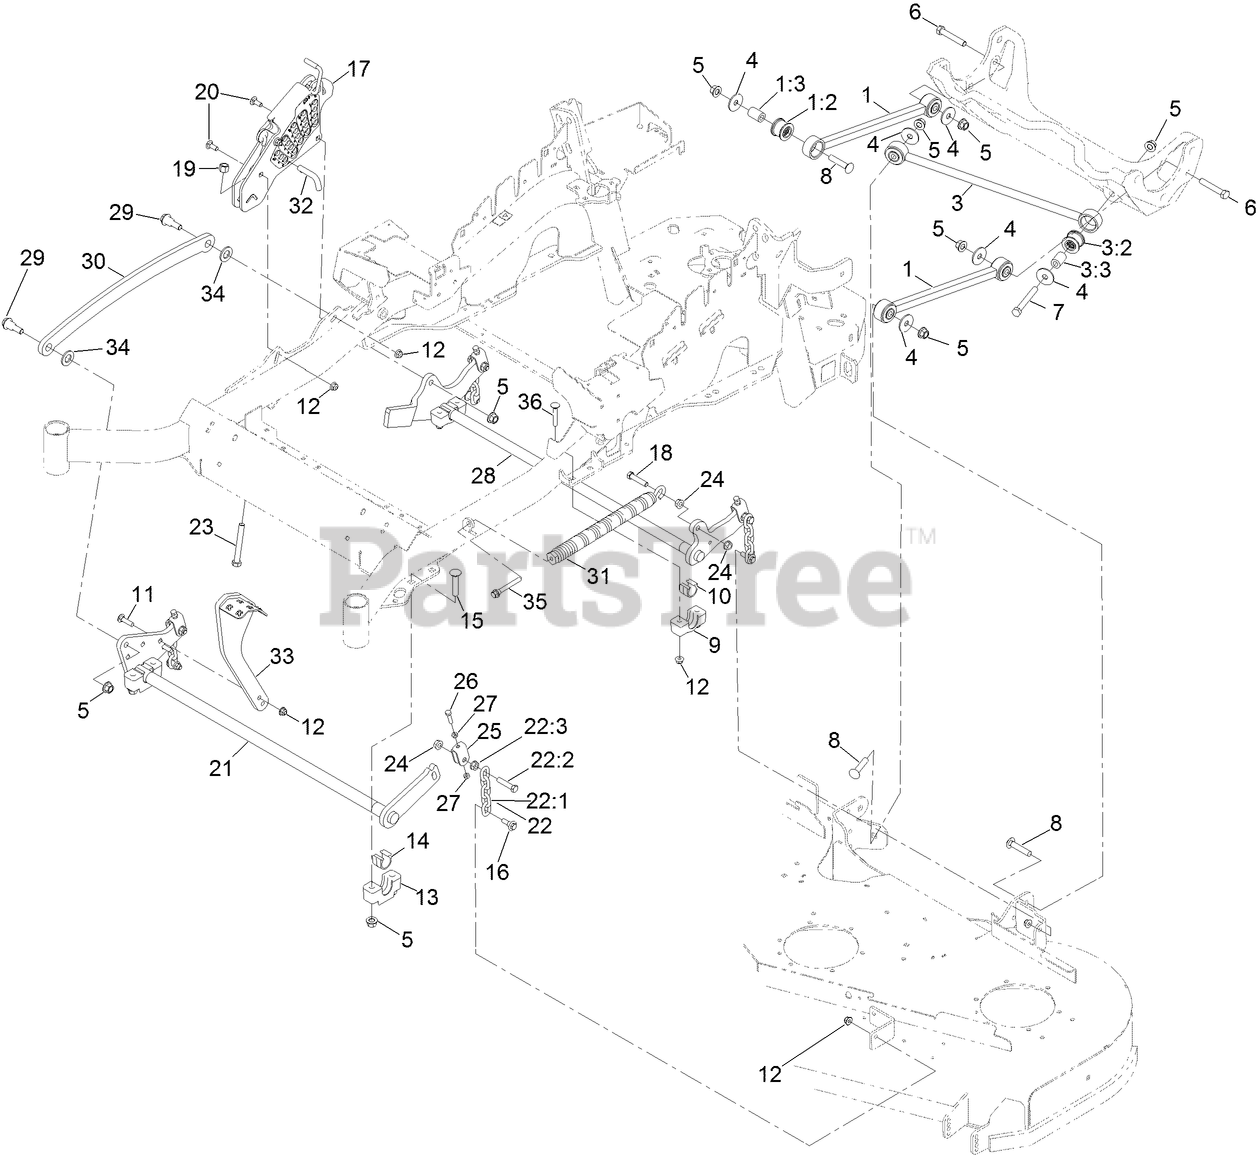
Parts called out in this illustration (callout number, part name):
1	LONG STRUT ASM
1:2	BUSHING-SUSPENSION, RUBBER
1:3	SPACER
3	PANHARD ROD ASM
3:2	BUSHING-SUSPENSION, RUBBER
3:3	SPACER
4	WASHER-THRUST
5	NUT-LOCK
6	SCREW-HH
7	SCREW-HH
8	SCREW-CARR
9	SUPPORT-CROSS SHAFT, BEARING REAR
10	BEARING-CROSS SHAFT, REAR
11	SCREW-CARR
12	NUT-HF, NI
13	SUPPORT-CROSS SHAFT, BEARING
14	BEARING-CROSS SHAFT, FRONT
15	BOLT-CARR
16	SCREW-SHOULDER, HHF
17	HOC ASM
18	SCREW-HH
19	NUT-LOCK, NI
20	BOLT-CARR
21	DECKLIFT-FRONT
22	DECK LIFT CHAIN ASM
22:1	CHAIN-LIFT, DECK
22:2	SCREW-HH
22:3	NUT-HF
23	BOLT-TAP
24	NUT-HF
25	YOKE-ADJUST, DECK
26	SCREW-HH
27	NUT-JAM
28	LIFT-DECK, REAR
29	SCREW-SHOULDER, HHF
30	LINK-LIFT, DECK
31	SPRING-EXTENSION
32	PIN-HOC
33	LEVER-FOOT
34	WASHER-FLAT
35	BOLT-SHOULDER
36	SCREW-CARR
